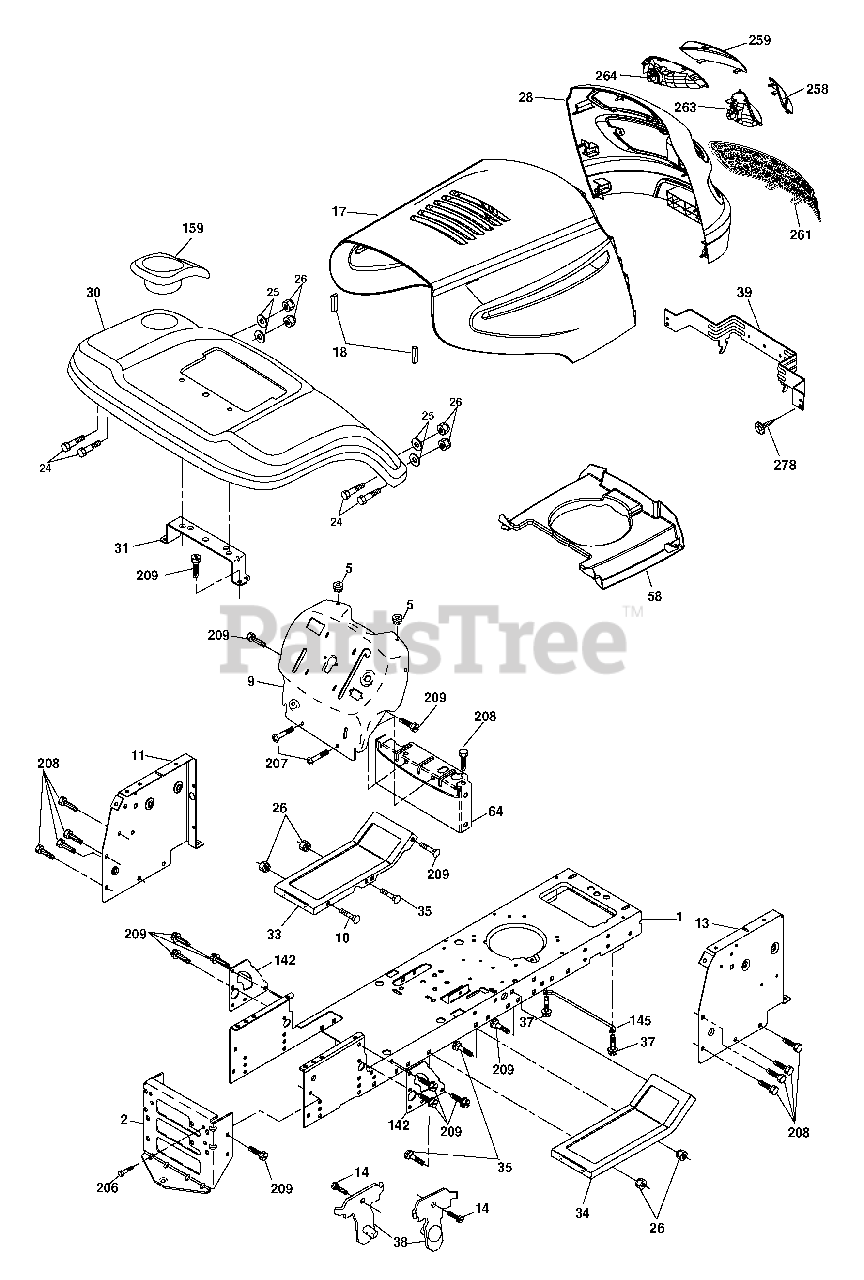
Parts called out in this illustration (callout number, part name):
2	Drawbar
5	Dash
14	Hood
15	Lens Grille LH
18	Grille
25	Lens Grille RH
68	Screw THDROL 5/16-18 x 1/2
99	Rod Bypass Asm
130	Screw 10 x 3/4 Single Lead-Hex
137	Bumper Hood
138	Cupholder
150	Duct Heat Hood
151	Bracket Pivot
152	Shield Browning/Debris
159	Screw Hexwsh Thdrol 3/8-16 x 3/4
162	Screw Hex Wsh Hi-Lo 1/4 x 1/2 UNC
175	Crossmember
176	Screw 10-24 x 5/8 Wshd Qdrx
177	Bushing Steering
181	Bushing Mtg. Fender Crgo.
182	Dash Lower
183	Bolt Fin Hex 5/16-18 x 1-1/4
184	Spacer Fender
189	Screw 5/16-18 x 3/4
194	Nut Lock Hex Flange 5/16-18
196	Console Asm. Deck Lift
197	Rod Pivot Chassis
207	Bezel RH
208	Bezel LH
219	Stud Fastener
222	Screw thd Roll 1/4-20 x 5/8
229	Screw 3/8-16 x 1
230	Bolt Shoulder 5/16-18
